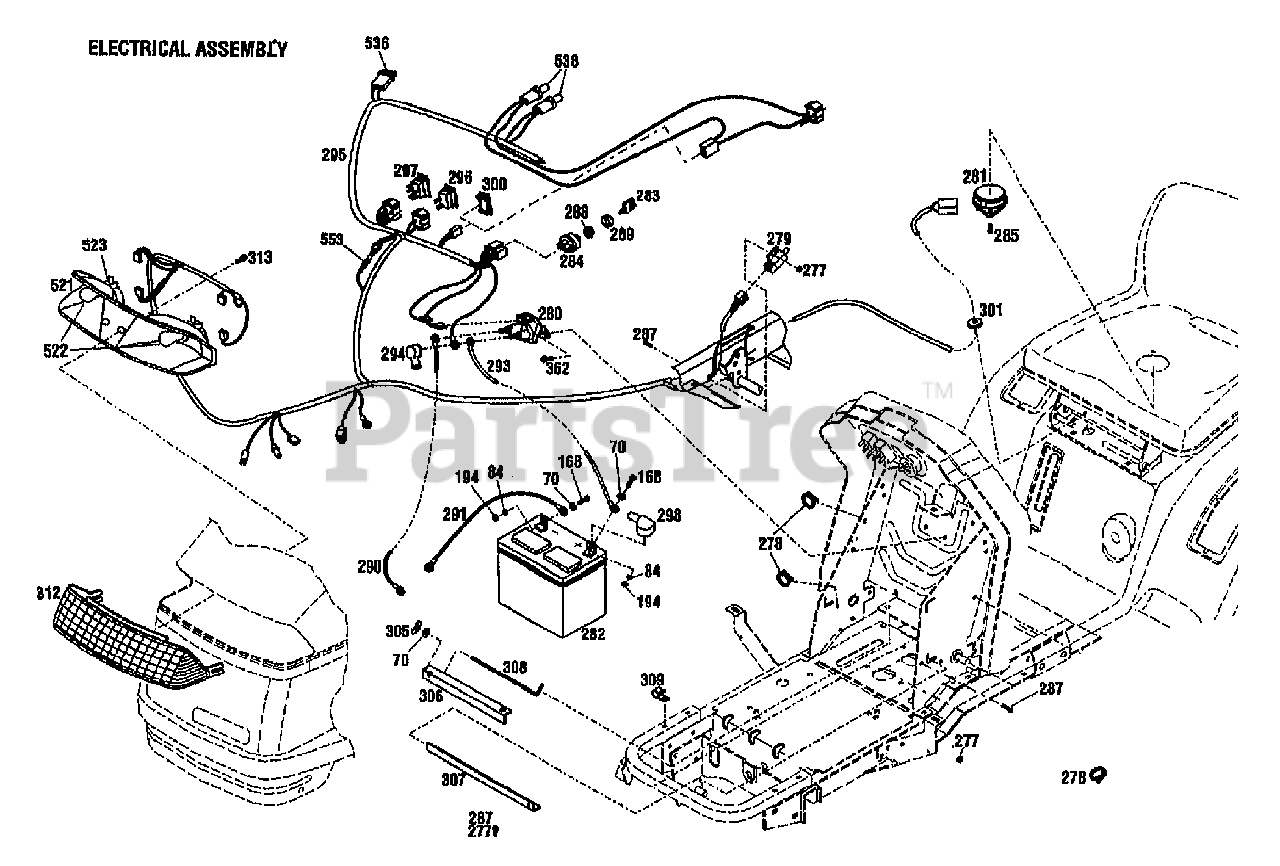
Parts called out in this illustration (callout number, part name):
70	WASHER-FLAT 1/4 SAE
84	WASHER-LK .25 ZP
168	SCR-HH 1/4-20X.75 G5 ZP
194	NUT-HEX 1/4-20 ZP
277	NUT W/LKWASHER 10-24 ZP
278	TIE-CABLE NYLON BLACK
279	SWITCH
280	SOLENOID
281	SWITCH-SEAT
282	BATTERY (13085,13086)
283	KEY-IGNITION
284	SWITCH-IGNITION
285	SCR-PHP 1/4-20X.50 ZP
287	SCR-HHS 10-24X.625 ZP
288	NUT-SWITCH
289	CAP-SWITCH
290	CABLE-STARTER
291	CABLE-BATTERY (-)
293	CABLE-BATTERY
294	BOOT-SOLENOID
295	HARNESS-MAIN {13085}
295	HARNESS-MAIN WIRING {13086}
296	SWITCH-LIGHT
297	SWITCH-PTO
298	BOOT-TERMINAL
300	COVER-SWITCH
301	GROMMET
305	NUT-WING
306	CLAMP-BATTERY
307	BRKT-BATTERY LOWER
308	SCR-HOOK
309	CLIP-J
312	LENSE-HEADLIGHT
362	SCR 1/4-20X.5 FL SELF TAP
521	HEADLGT-REFL (PART OF 1772002)
522	LIGHTBULB
523	SOCKET
536	FUSE
538	LIGHTBULB
553	ASSM-DIODE
